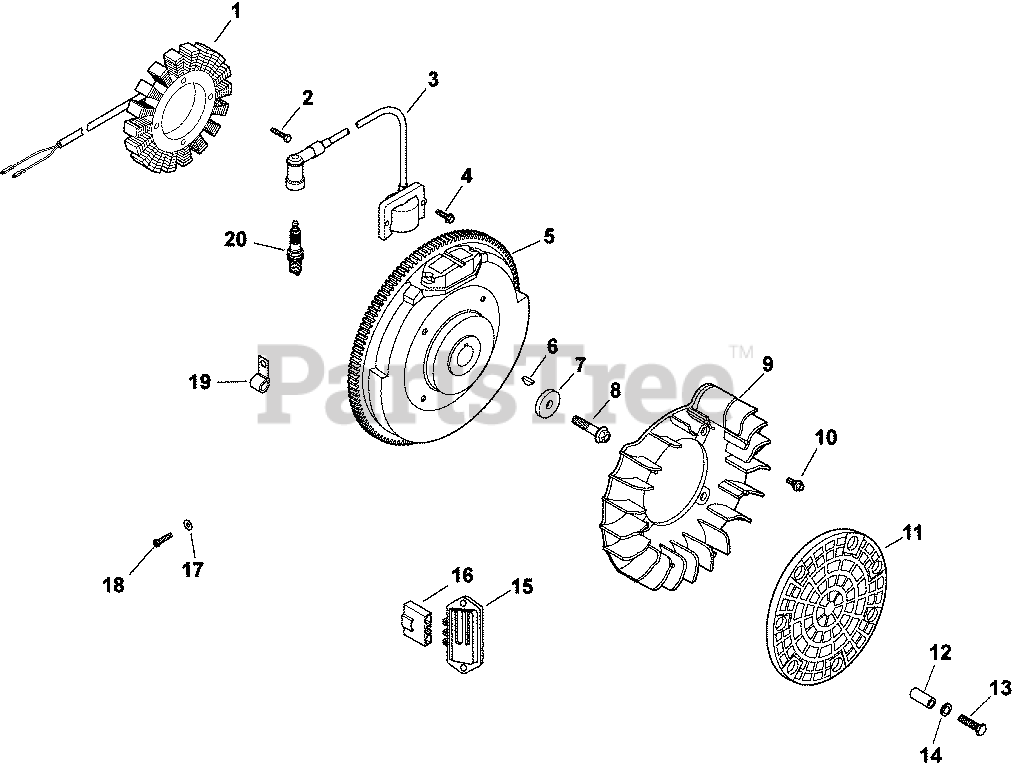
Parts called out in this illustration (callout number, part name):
1	KIT, 15 / 20 AMP STATOR
2	SCREW, M5X0.8X25 - (#25086402S)
3	MODULE, IGNITION-USE 24 584 45-S
4	SCREW, FLG THD FRM M5X.8X20-(#25086399S)
5	FLYWHEEL, PAINTED-USE 24 025 55-S
6	KEY, 3/16" X 5/8"
7	WASHER, FLAT 13/32"
8	SCREW, FLG M10X1.5X45 - (#25086361S)
9	FAN USE 24 157 11-S
10	BOLT, SHOULDER
11	KIT, GRASS SCREEN
12	SPACER - DISCONTINUED
13	SCREW, SLT HD CAP M4X0.7X25
14	WASHER, FLAT 1/4" (O.D. 1/2")
15	REG/RECTIFIER (20/25 AMP)-USE 25 403 20-S
16	CONNECTOR, BODY (KM)-USE 25 155 41-S
17	WASHER, FLAT 3/16"
18	SCREW, PHL HD #11-16X7/8"
20	PLUG, SPARK (STD)
